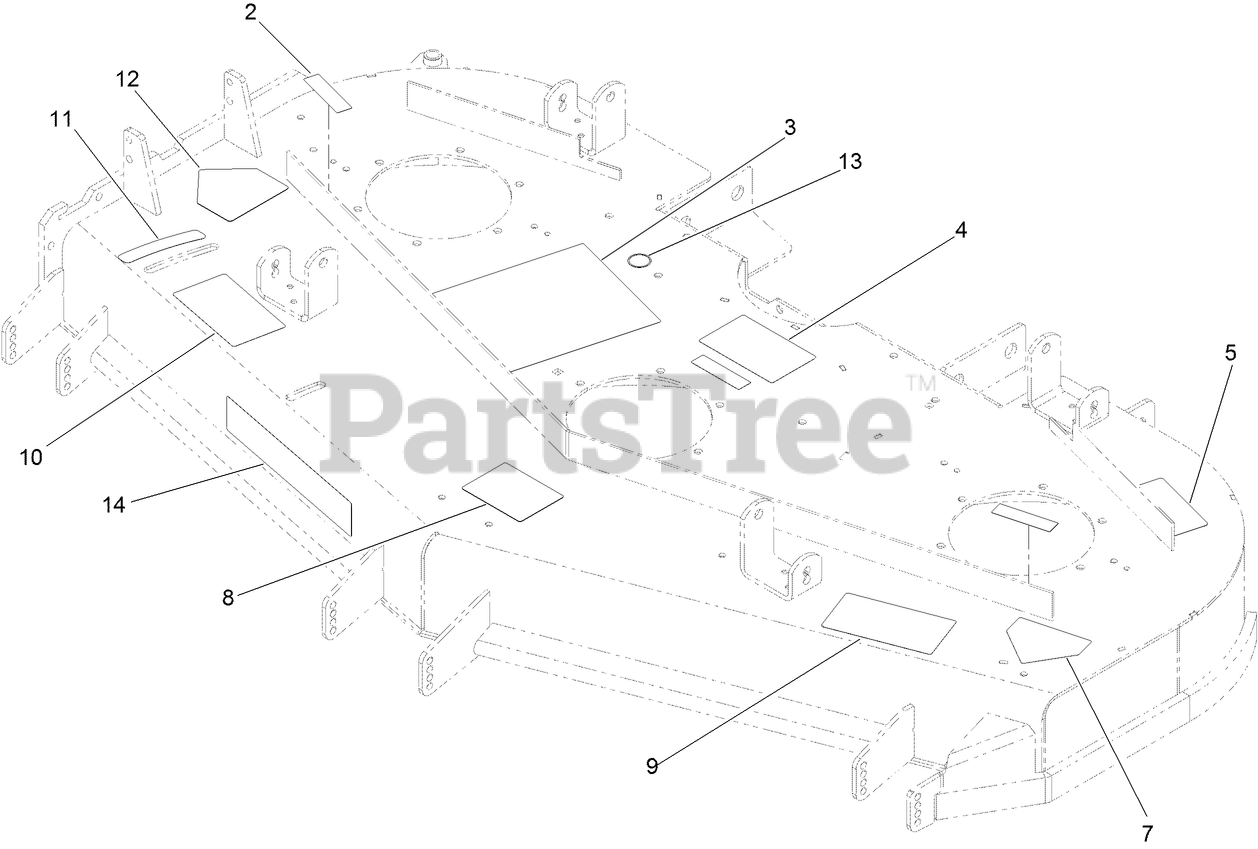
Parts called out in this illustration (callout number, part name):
2	DECAL-COVER, MISSING
3	DECAL-CHECK, SERVICE
4	DECAL-ROUTING, BELT
5	DECAL-TORQUE
7	DECAL-DANGER
8	DECAL-SCALP, ANTI
9	DECAL-DANGER, THROWN OBJECT
10	DECAL-ADJUSTMENT, BAFFLE
11	DECAL-SETTING, BAFFLE
12	DECAL-DANGER
13	DECAL-GREASE
